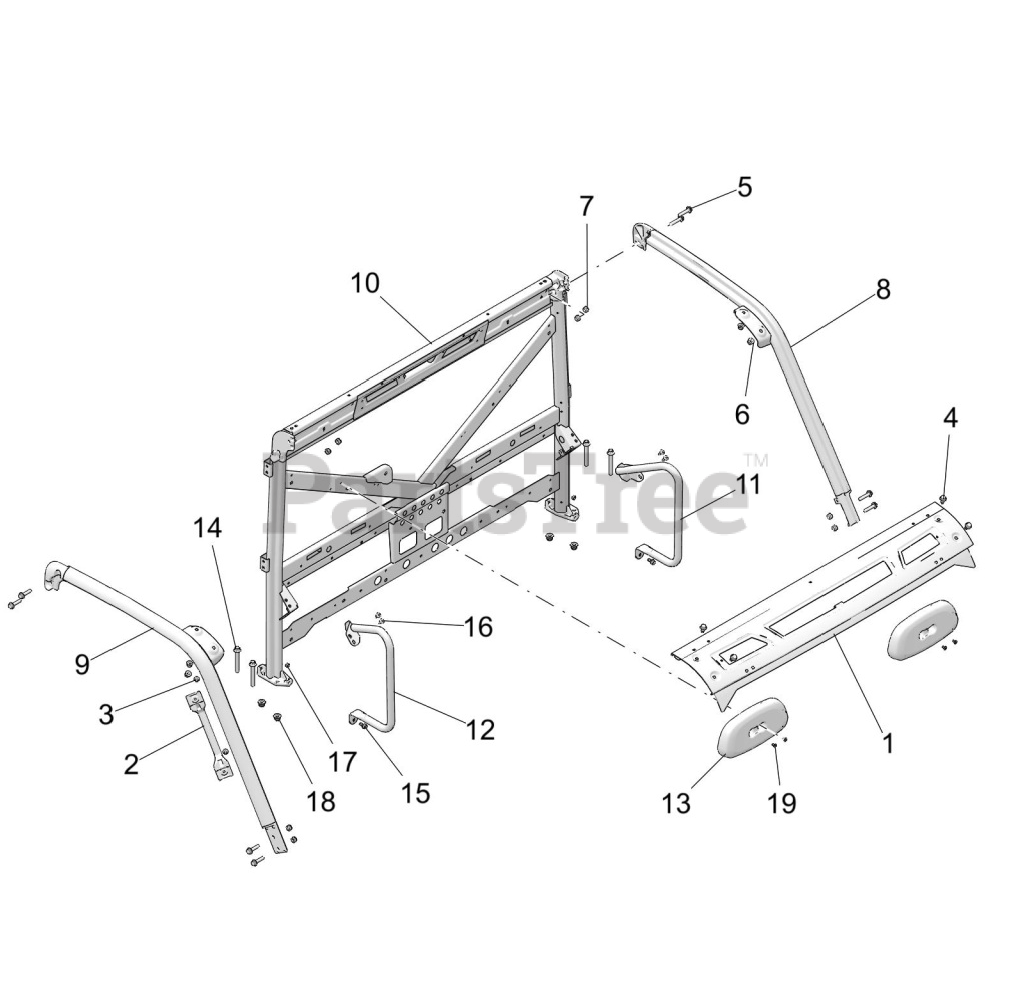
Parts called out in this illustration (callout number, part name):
1	K-PLATE,WSHLD MNT,UPR,ARN
2	HANDLE-GRAB,ROPS,BLK
3	BOLT-M8X1.25X20,HXFLG,TAP/R-OD
4	SCR-HXFL-M10X1.5X20 10.9 RIE P
5	SCR-HXFL-M10X1.5X45 10.9 RIE
6	NUT-HXFL-M10X1.5 8 ZB3 NYL
7	NUT-HEX-M10X1.5 10 ZB3 NYL
8	WELD-CAB FRAME,FRT,LH,M.BLK
9	WELD-CAB FRAME,FRT,RH,M.BLK
10	WELD-CAB FRAME,REAR,M.BLK
11	WELD-BOLSTER,LH, M.BLK
12	WELD-BOLSTER,RH, M.BLK
13	HEADREST-BLK
14	SCR-HXFL-M12X1.75X90 10.9 ZPC
15	SCR-HXFL-M8X1.25X20 8.8 ZOD P3
16	SCR-TXTH-M6X1.0X25 RIE
17	NUT-HEX-M8X1.25 10 P&O
18	NUT-HXFL M12X1.75 NYLOC ZOD
19	RIVET(50)
